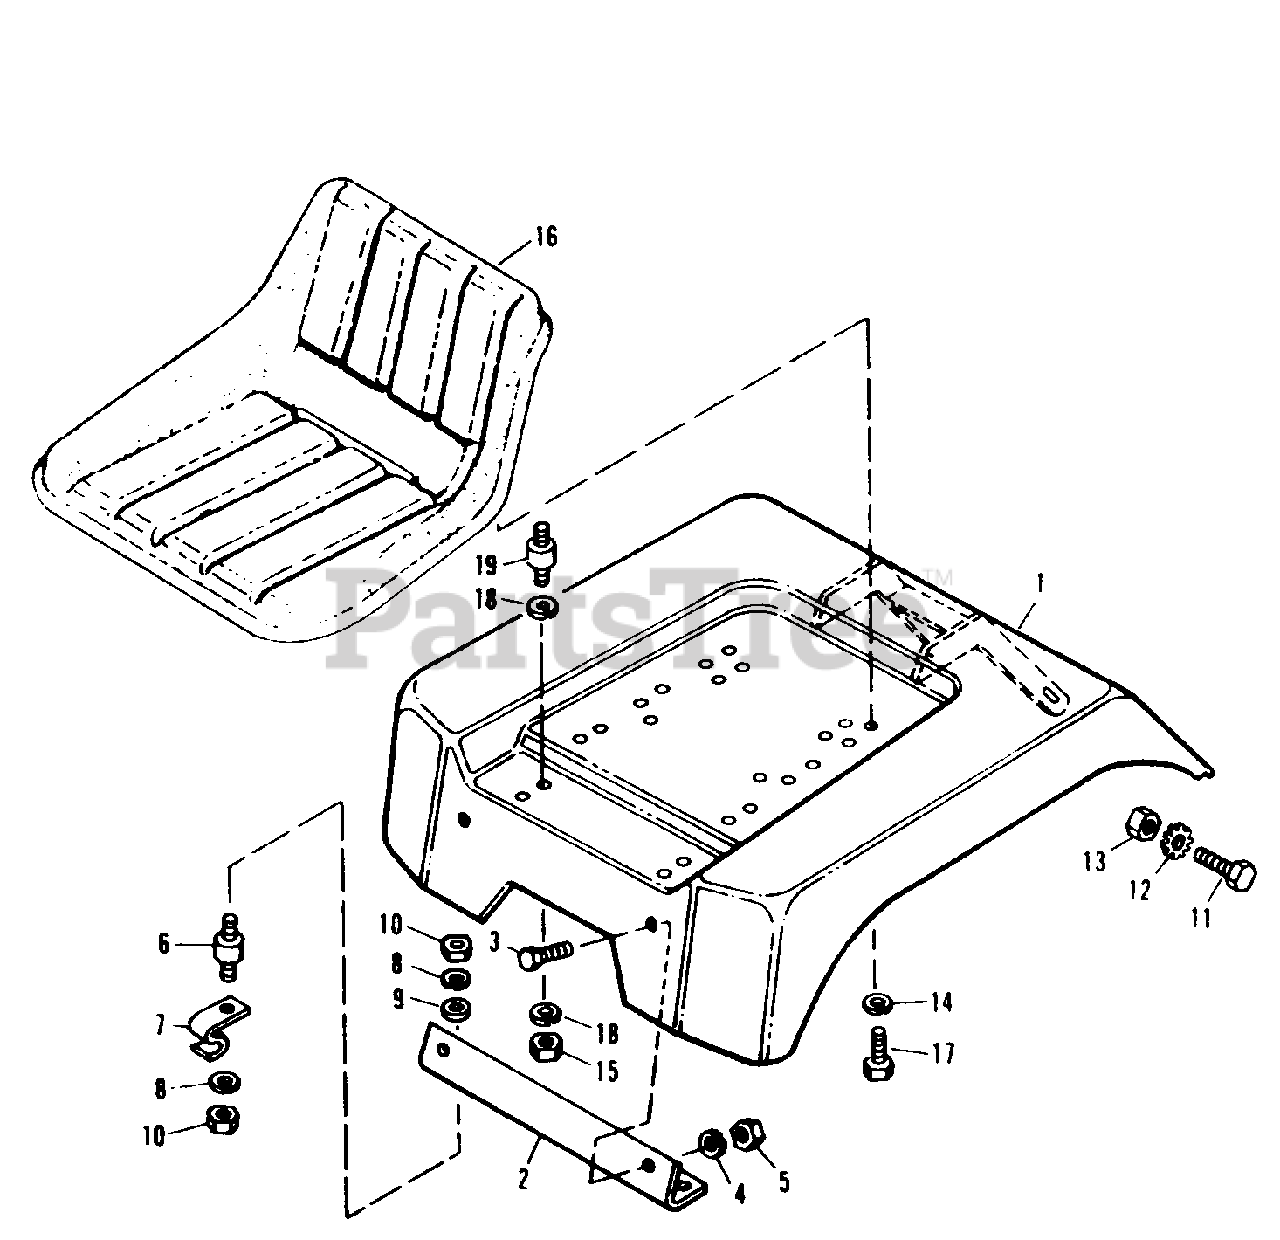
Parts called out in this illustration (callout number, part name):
1	Seat Deck Assy.
2	Seat Deck Bracket,Front
3	Hex Head Cap Screw, 5/16" 18 x 5/8"
4	Lock Washer, 5/16"
5	Hex Nut, Full, 5/16"-18
6	Cushion Connector, Front
7	Spring Clip
8	Lock Washer, 5/16"
10	Hex Nut, Full, 5/16"-18
11	Hex Head Capscrew, 3/8"-16 x 1-1/4"
12	Lock Washer
13	Hex Lock Nut, Full, 3/8"-16
14	Lock Washer, 5/16"
15	Hex Nut, Full, 5/16"-18
16	Contour Seat Assembly
17	Hex Head Capscrew, 5/16"-18 x 5/8"
18	Lock Washer, 5/16"
19	Cushion Connector
